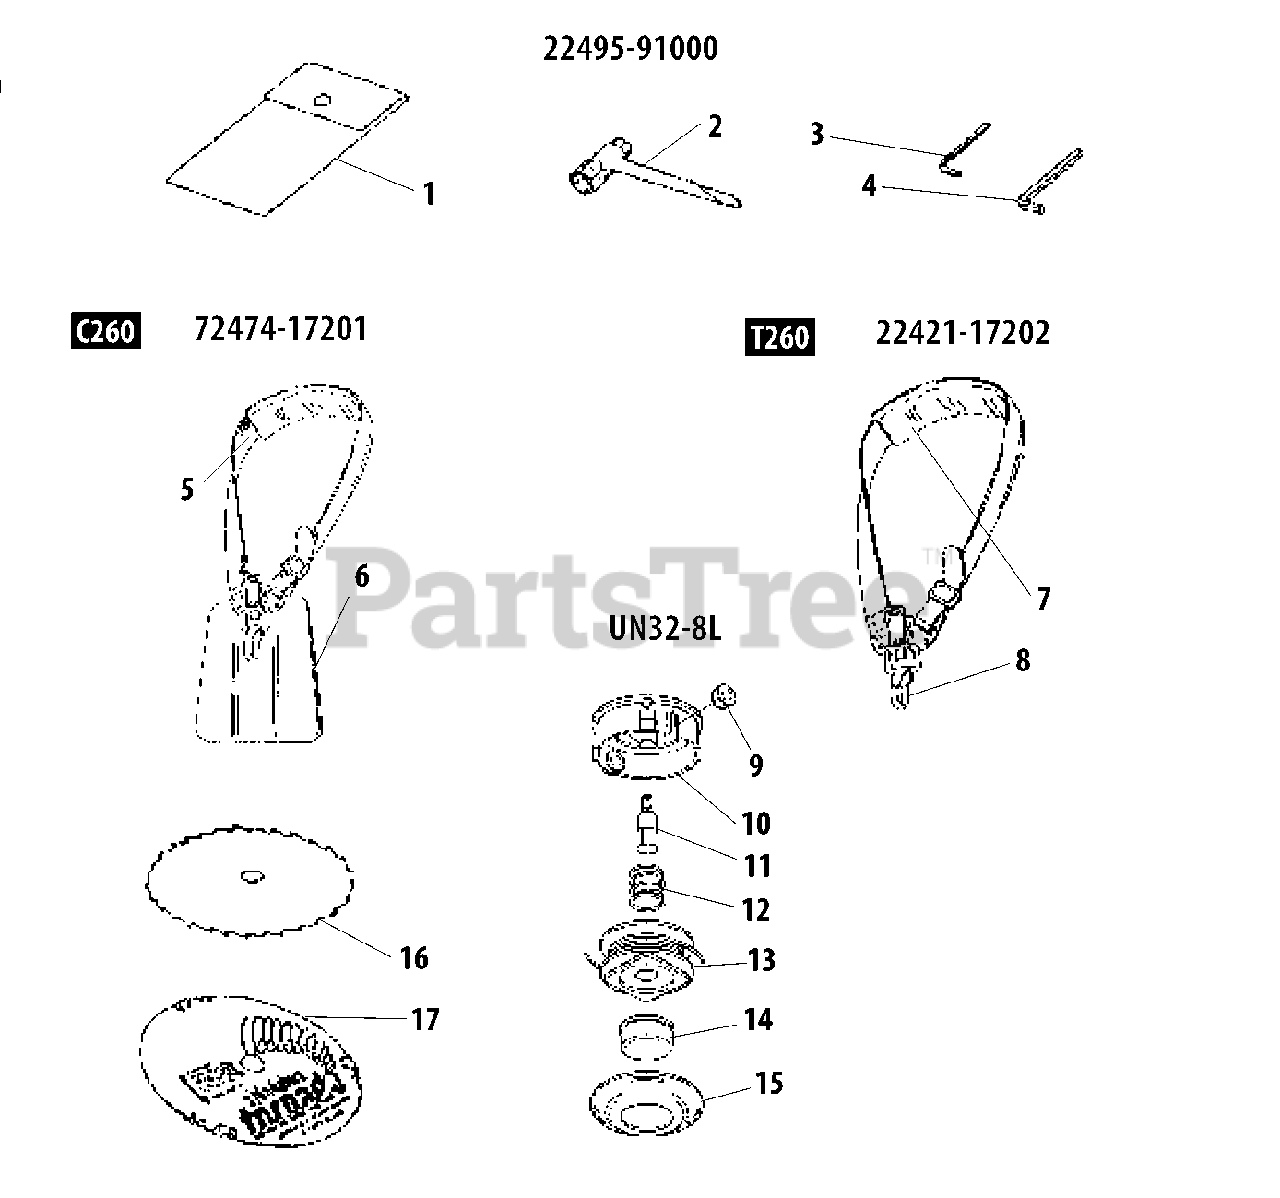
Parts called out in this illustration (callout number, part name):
1	BAG, TOOL
2	T-WRENCH 13×19 MM
3	WRENCH, ALLEN 3 MM
4	WRENCH, ALLEN 4 MM
5	PAD, SHOULDER
6	PAD
7	PAD, SHOULDER
8	HOOK
11	SHAFT BOLT
16	BLADE, 25 MM ID - 30 TOOTH -- 8"
17	BLADE - 6 TOOTH -- 9" TORNADO
A	SERVICE TOOL KIT
A	HARNESS ASSY, BRUSHCUTTER
A	HARNESS ASSY, SHOULDER
A	TRIMMER HEAD ASSY
